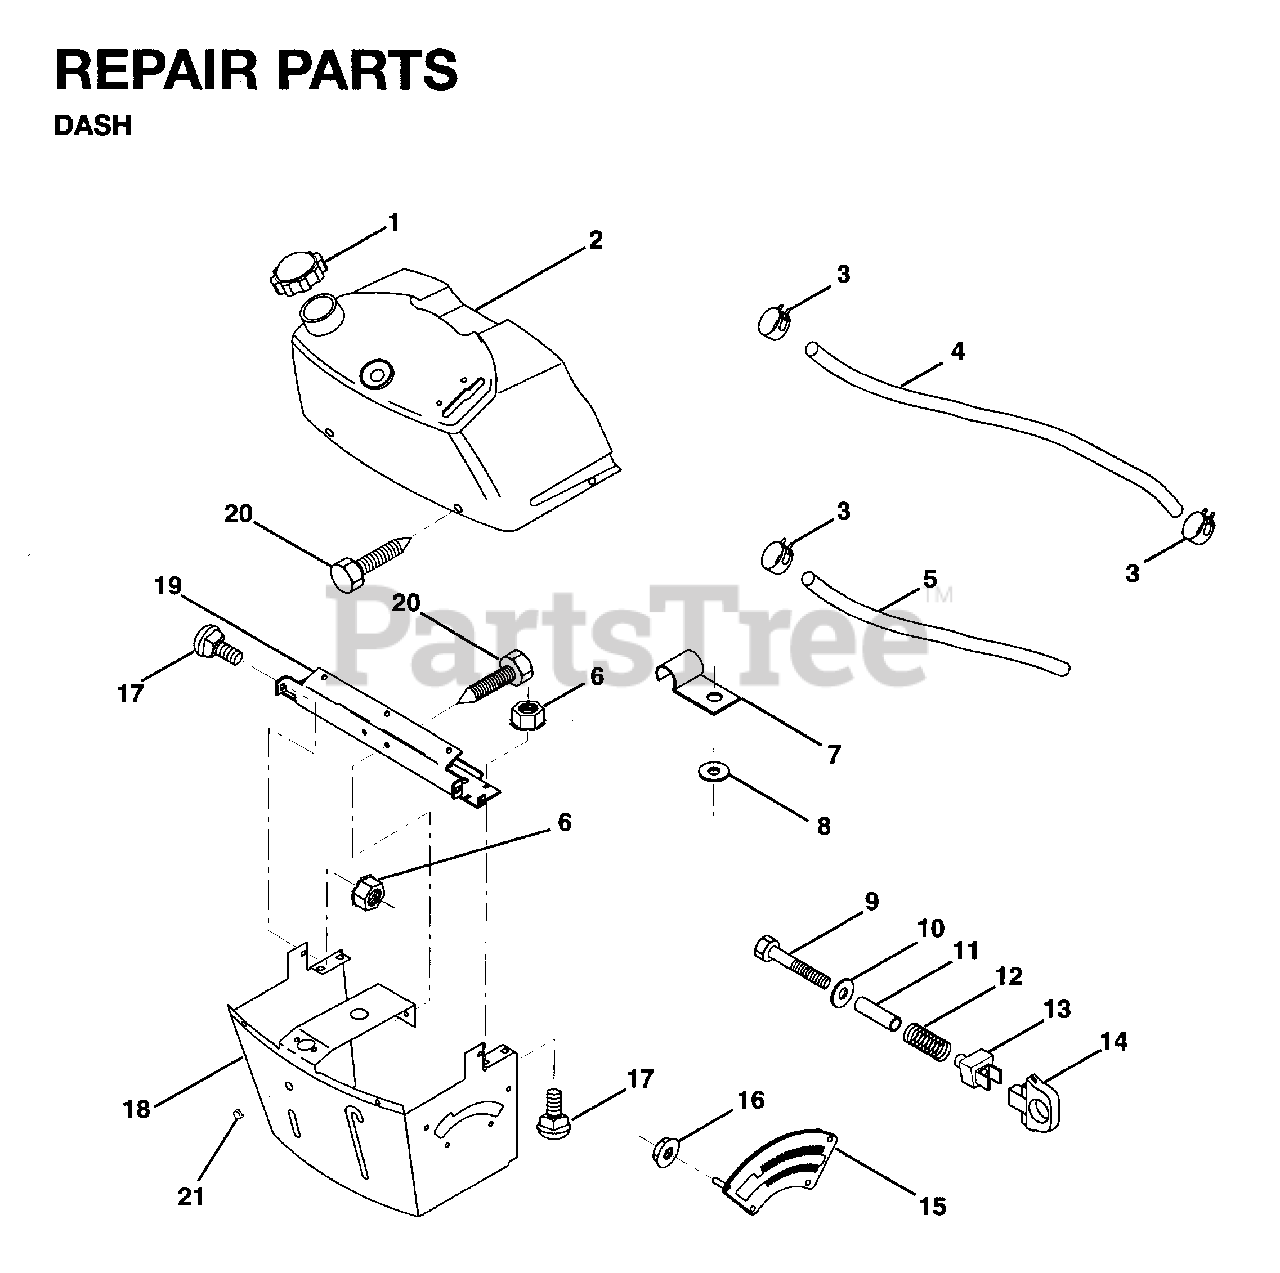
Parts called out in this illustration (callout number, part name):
3	HOSE CLAMP
4	FUEL LINE
5	FUEL LINE T
6	NUT.CROWNLOCK.1/4
7	CLIP T
8	WASHER - 26X6.5X1.6
9	BOLT HEX FIN 1/4-20X1 3/4
11	SPACER SPLIT
12	SPRING.COMPRESSION
13	KNOB HGT RETAINER
14	KNOB
15	ADJUSTER QUAD
18	SUPT ASSY DASH
19	CROSS BRACE
21	PLUG DOME
